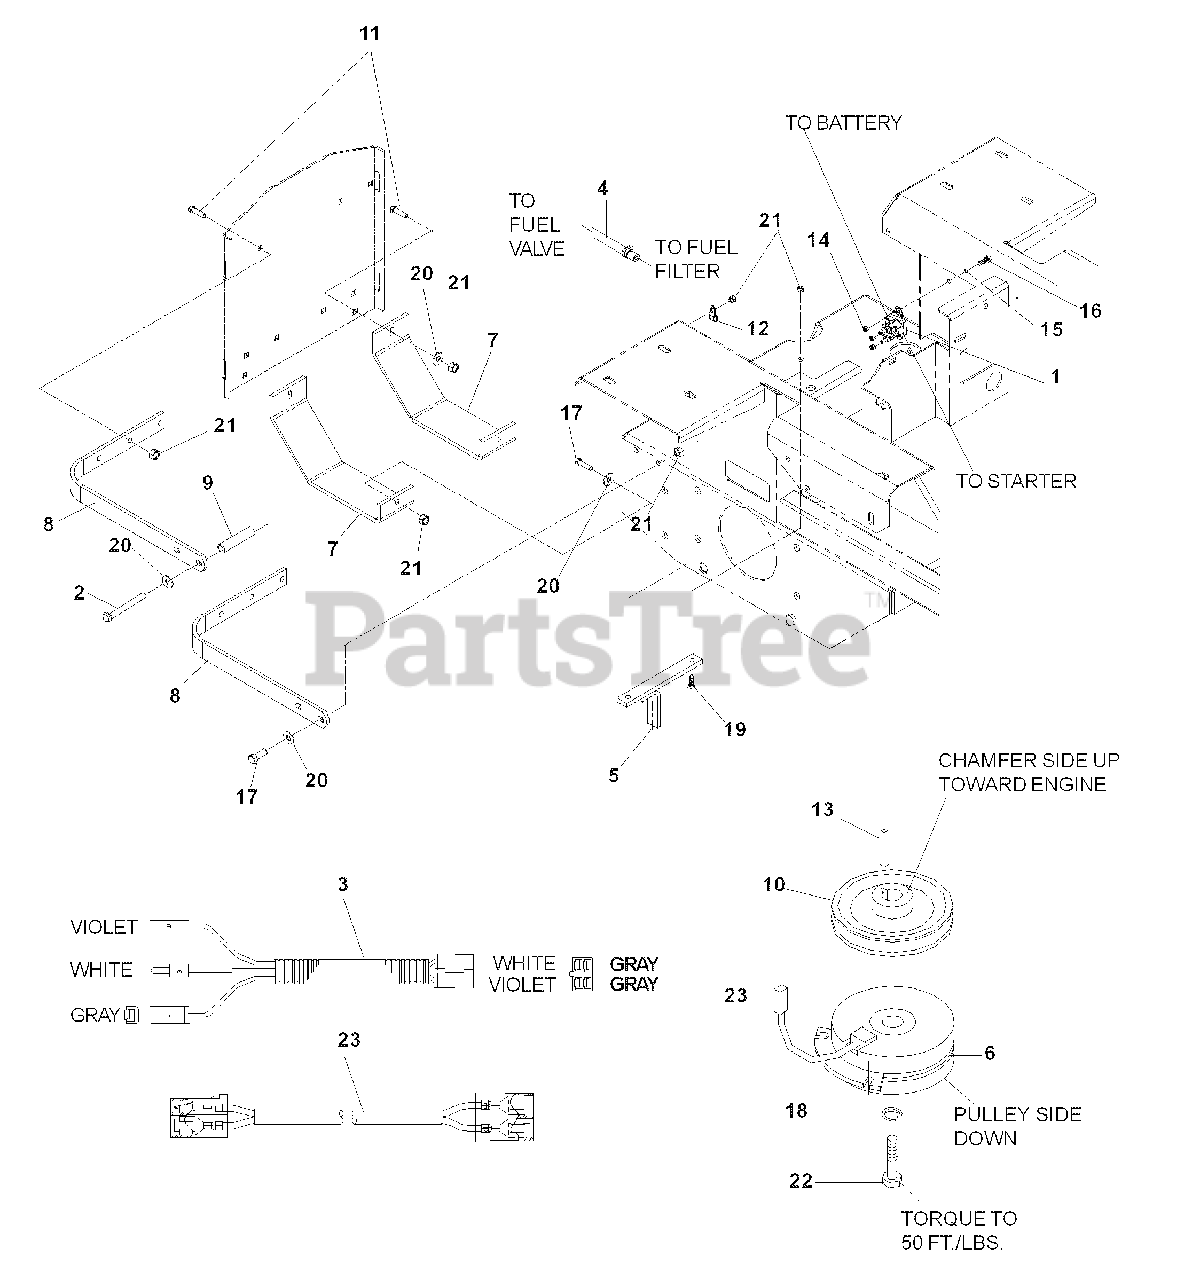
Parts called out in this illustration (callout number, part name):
2	HCS, 5/16-18 x 4
3	PIGTAIL, KAWASAKI
4	FUEL LINE HOSE
5	CLUTCH TIE DOWN
6	CLUTCH MODELS 968999254, 968999255
7	SKID PLATE
11	RHSNB, 5/16-18 x 1
12	CLAMP, DOUBLE TUBE
13	KEY, 1/4 SQ x 1 1/4
14	NUT, 1/4-20, NYLOC
15	ASHER, 1/4
16	HCS, 1/4 -20 x 5/8
17	HCS, 5/16-18 x 1
18	LOCKWASHER, 7/16
19	HCS, 5/16-18 x 1 3/4
20	WASHER, 5/16
21	NUT, 5/16-18, NYLOC
22	HCS, 7/16-20 x 2 1/2
23	CLUTCH HARNESS
